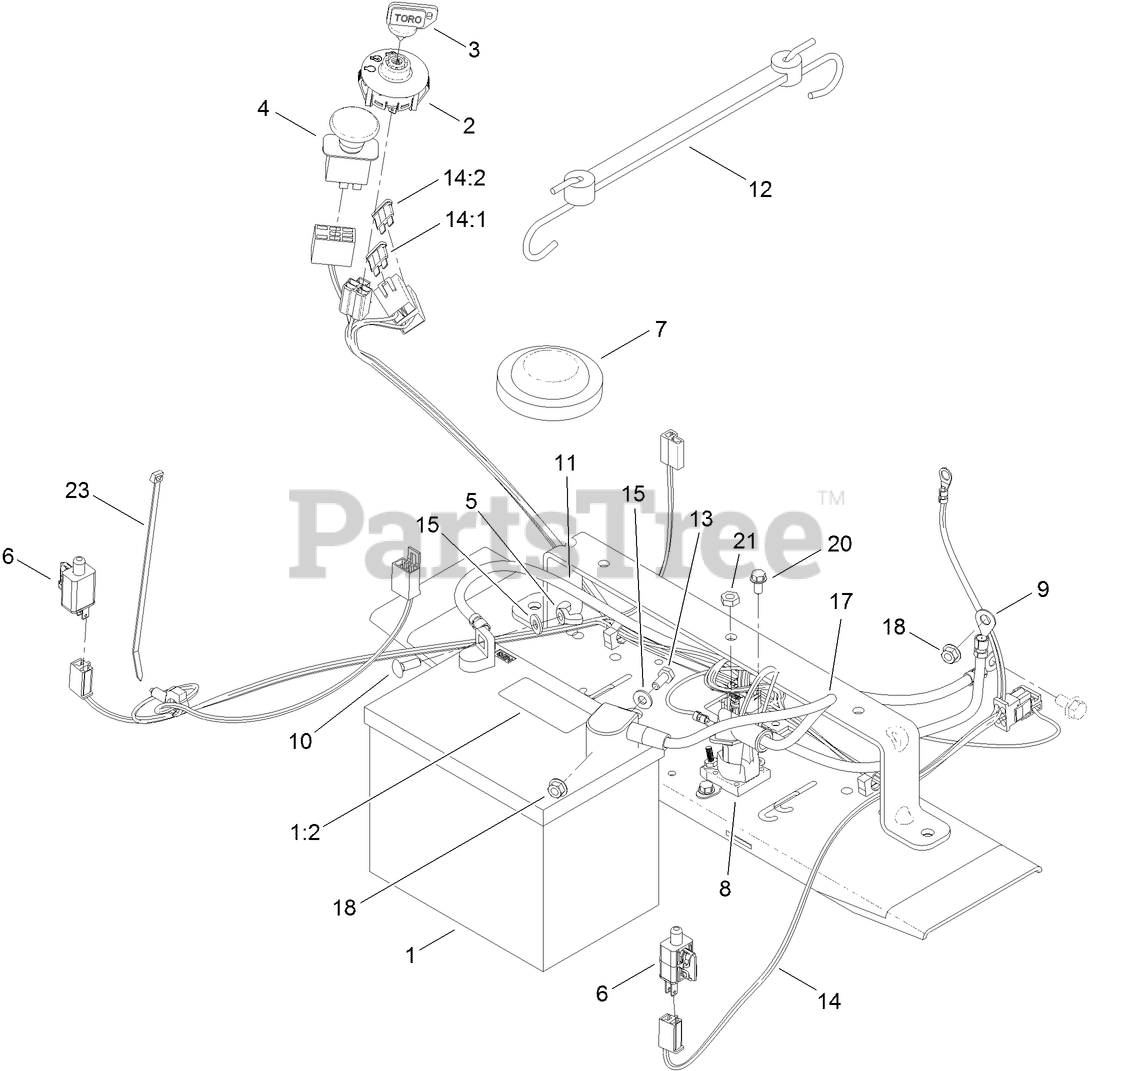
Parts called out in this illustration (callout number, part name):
1	BATTERY
1:2	Decal-Battery
3	KEY-IGNITION
4	SWITCH-PTO
5	NUT-WING
6	SWITCH
7	SWITCH-SEAT
8	SOLENOID
9	CABLE-BATTERY, RED
10	BOLT-CARR
11	CABLE-BATTERY, BLACK
12	HOLDDOWN-BATTERY
13	SCREW-HH
14:1	FUSE-BLADE, 30 AMP
14:2	FUSE-BLADE, 25 AMP
15	WASHER-FLAT
17	CABLE-BATTERY, RED
18	NUT-HF
20	SCREW-HWH
21	NUT-JAM
23	TIE-CABLE
